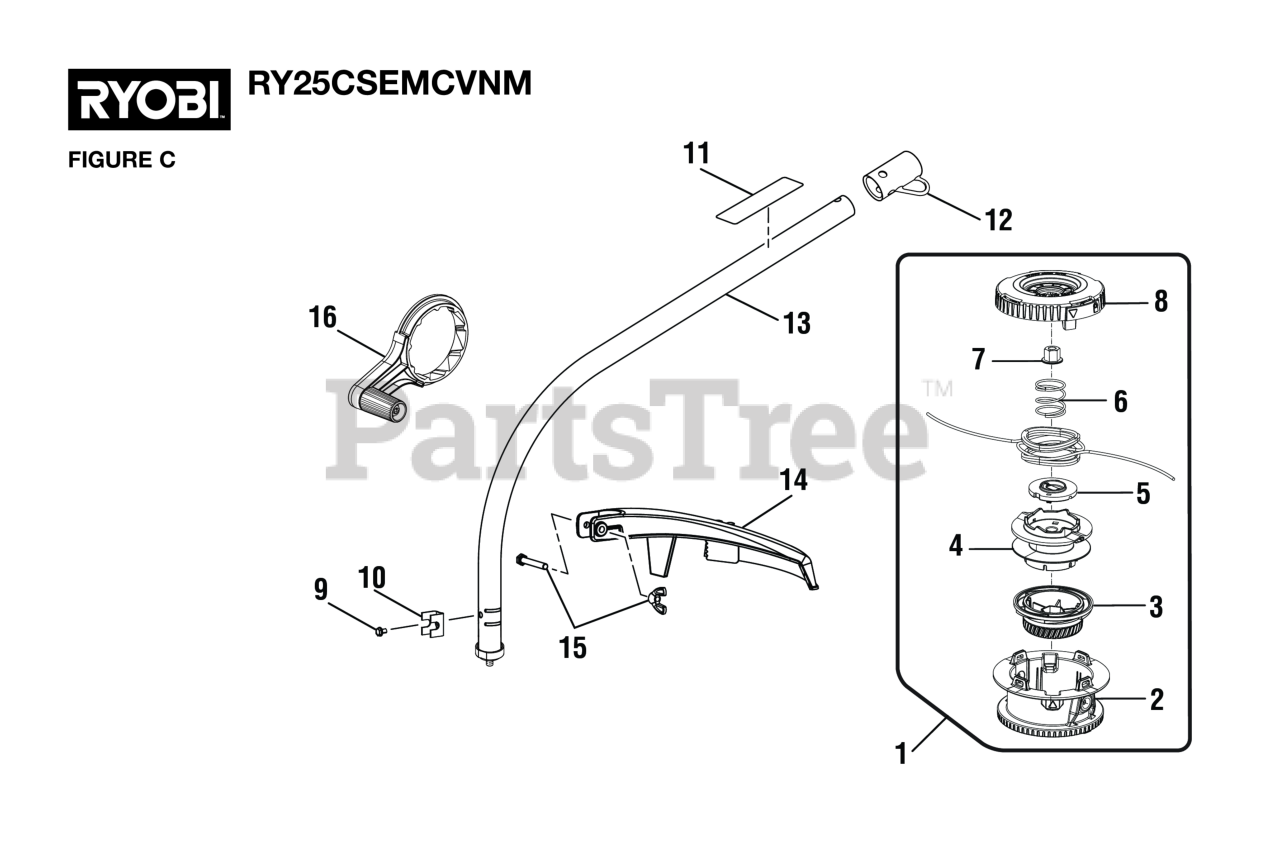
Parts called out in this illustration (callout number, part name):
1	Trimmer Head Assembly (.095) (Inc. Key Nos. 2-8)
2	Bump Head
3	Bump Knob (Green)
4	Spool Assembly
5	String Guide
6	Compression Spring
7	Flange Nut (M8)
8	Locking Assembly
9	Screw (#10-32 x 3/8 in., Hex Washer Hd. S.T.)
11	Warning Icon Label
12	Storage Hanger Cap
13	Curved Shaft Assembly (Inc. Key Nos. 9-12)
14	Grass Deflector Assembly
15	Fastener Parts Kit
16	Crank Handle
